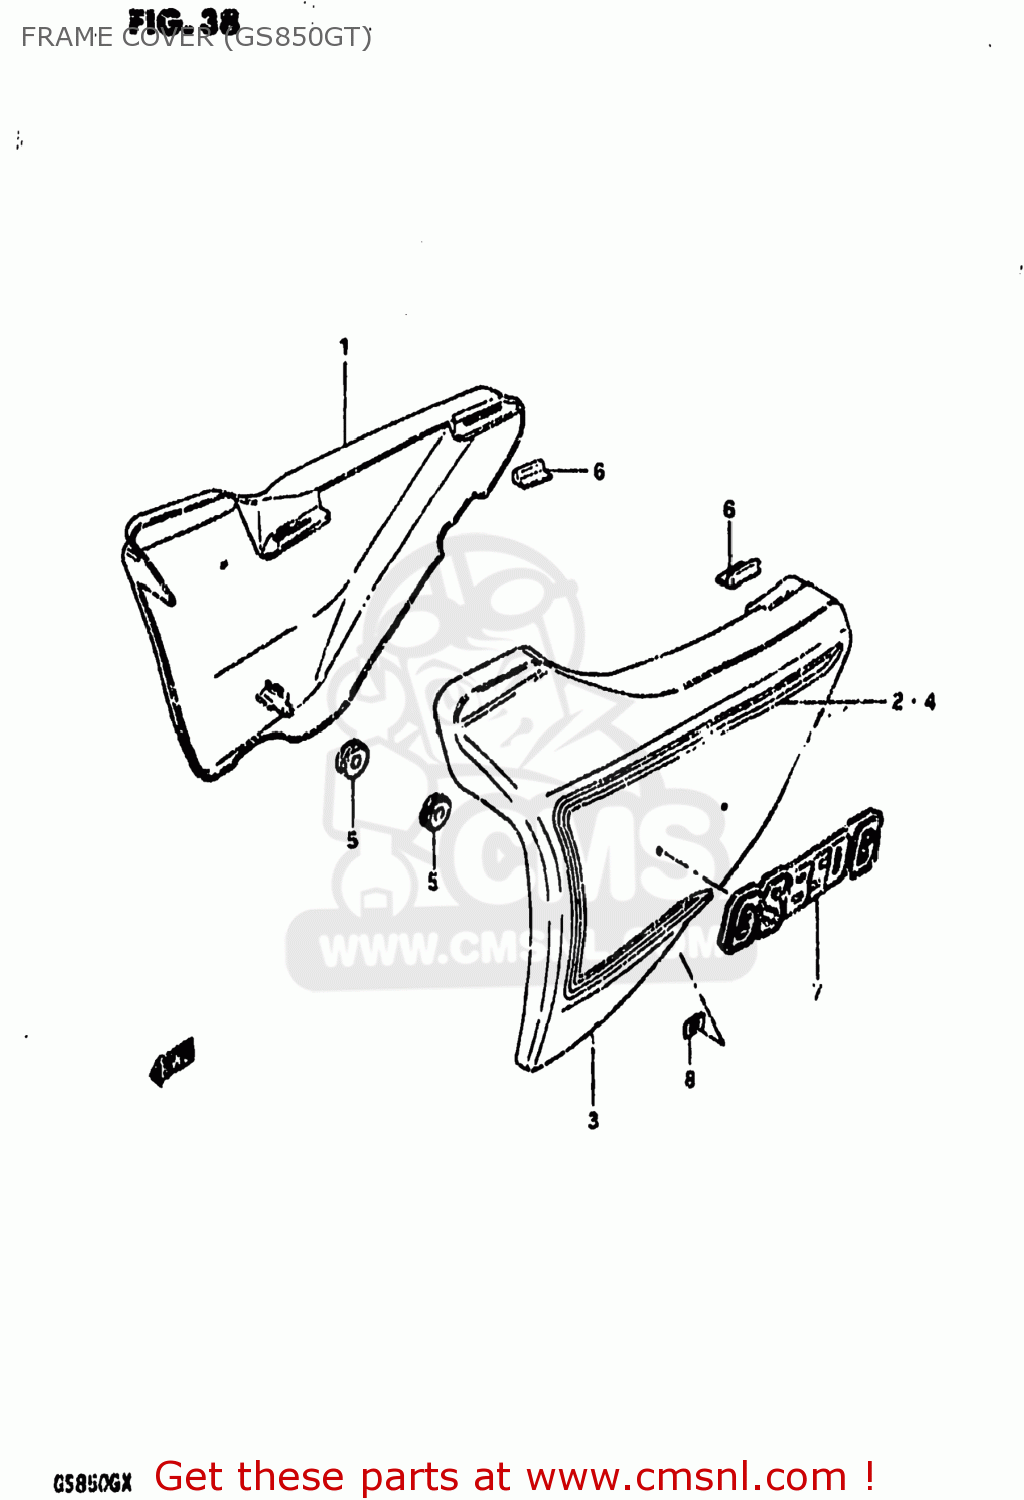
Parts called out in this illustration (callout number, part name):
1	COVER ASSEMBLY,FRAME,RIGHT
2	TAPE,FRAME COVER
3	COVER ASSEMBLY,FRAME,LEFT
4	TAPE,FRAME COVER
5	CUSHION
6	CUSHION,FRAME COVER
7	EMBLEM,FRAME COVER
8	NUT
